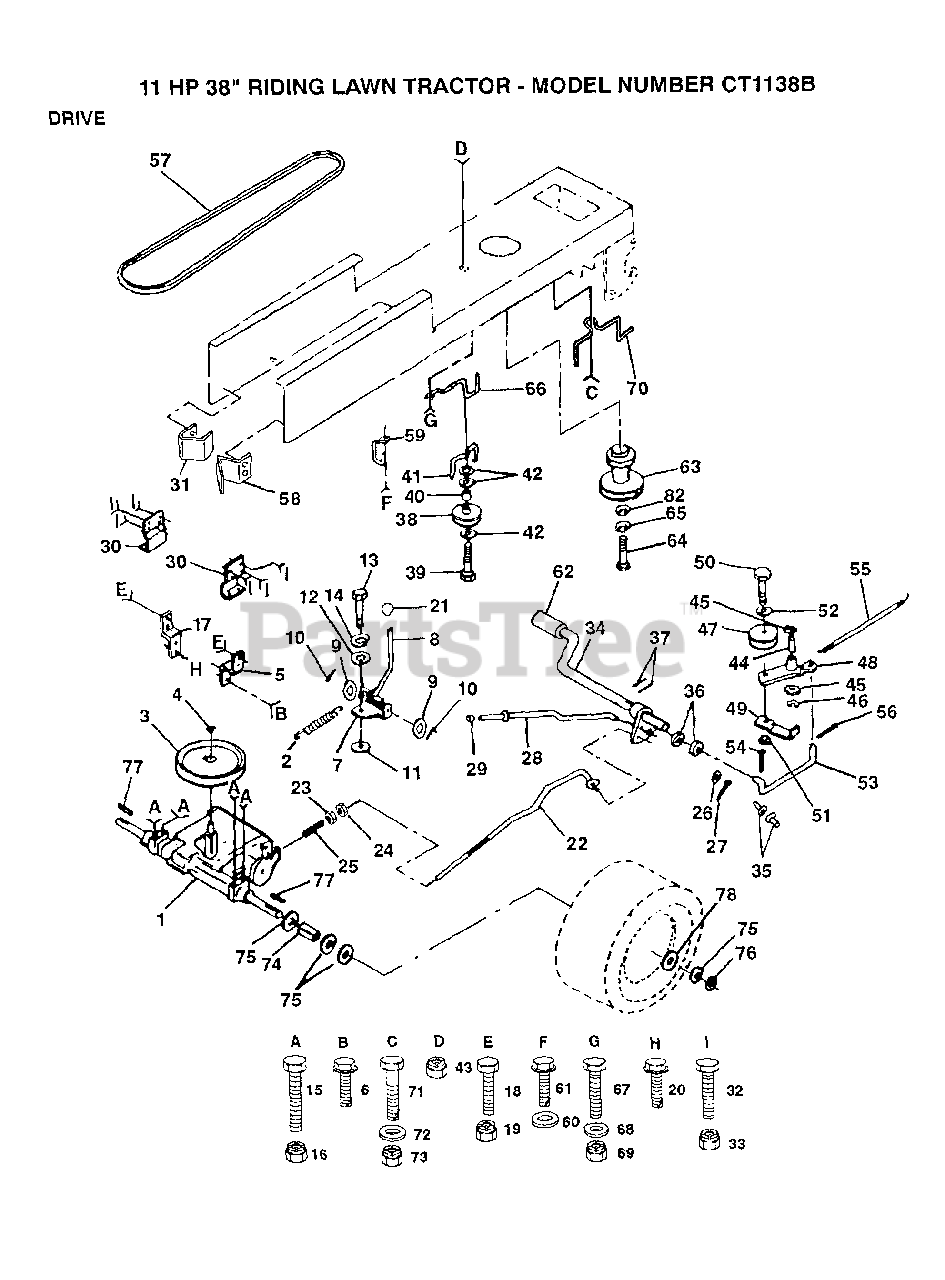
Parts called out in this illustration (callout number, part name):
3	PULLEY TRANS
5	STRAP TORQUE
6	SCREW
7	PLATE SHIFT LT
8	ROD SHIFTER
9	WASHER
10	PIN COTTER 1/8
11	WASH-SHFT PLT LT
12	WASHER LT
14	LOCKWASHER
15	BOLT
17	STRAP TORQUE
20	SCREW
21	KNOB T (1/2-HOLE)
23	NUT
24	NUT
25	SPRING ROD LT
26	WASHER
27	COTTER PIN
28	PARKING BRAKE ROD
29	PLUNGER CAP T
30	BRACKET LT
31	"KEEPER,BELT LH T"
35	NYLON BEARING
36	WASHER LT
38	PULLEY.IDLER.FLAT
39	BOLT
40	SPACER T
41	BELT KEEPER LT
42	WASHER
44	"LY, BEARING"
45	WASHER LT
46	KLIP RING
48	ARM IDLER
49	RETAIN BELT
52	WASHER
53	"LINK, CLUTCH T"
54	COTTER PIN
55	"SPRING, RETURN LT"
56	COTTER PIN
57	BELT-V.90.0.GD.DR
58	"KEEPER,BELT RH T"
60	WASHER
61	SCREW
62	PEDAL COVER T
65	LOCKWASHER
66	KEEPER.BELT.ENG.L
67	BOLT
68	WASHER
70	GUIDE BLT DR MWR
71	BOLT
72	WASHER
74	SPACER LT
75	WASHER
76	E-RING LT
77	SQUARE KEY
78	WASHER
82	WASHER
